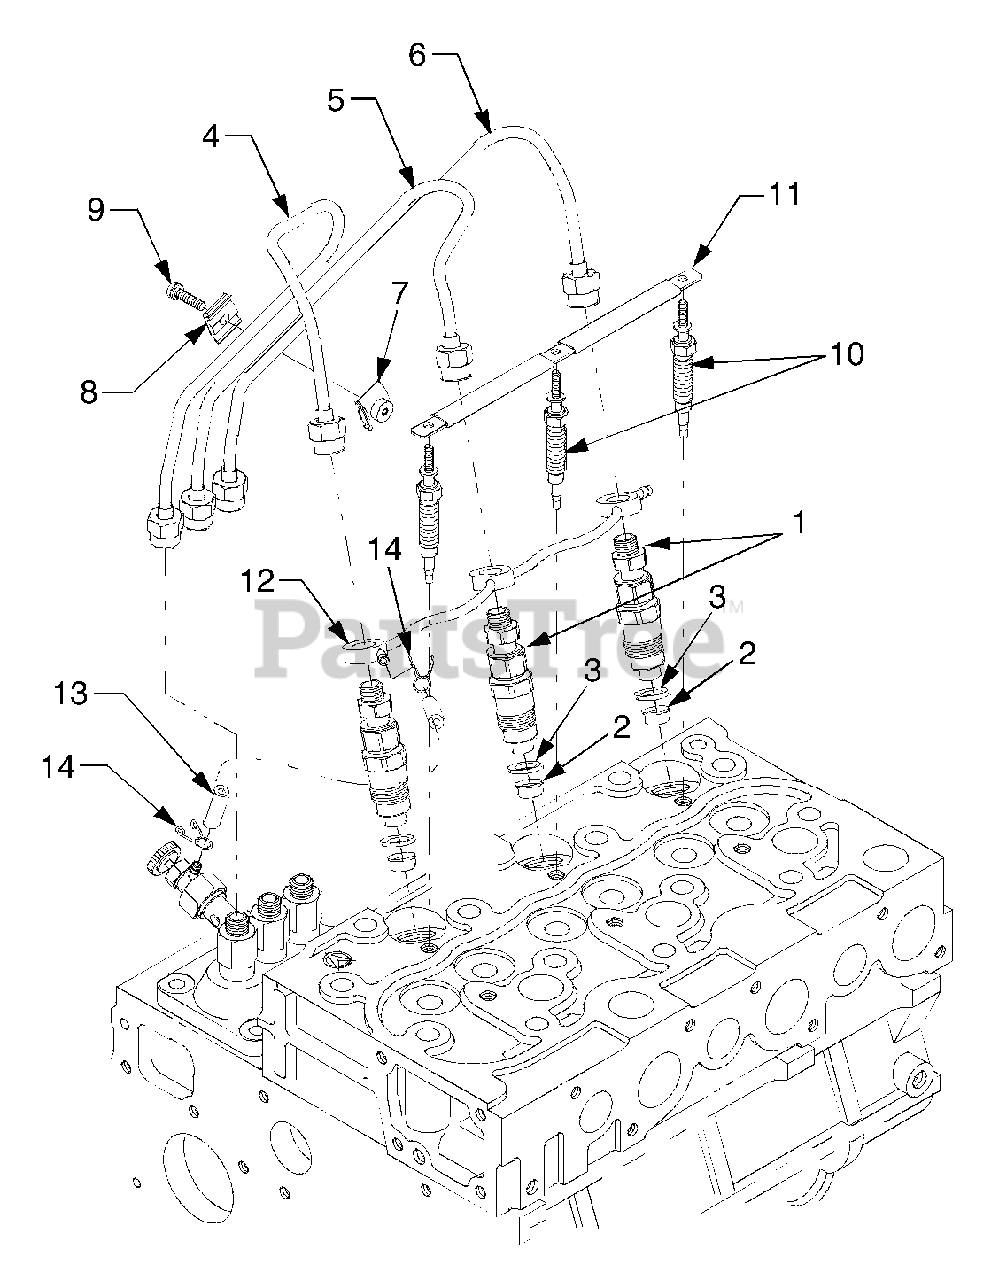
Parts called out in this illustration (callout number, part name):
1	Nozzle Holder Ass'y
4	Pipe 1, Injection
5	Pipe 2, Injection
6	Pipe 3, Injection
7	Clamp 1, Pipe
8	Clamp 2, Pipe
10	Plug, Glow
11	Cord, Glow Plug
12	Over Flow Pipe Ass'y
